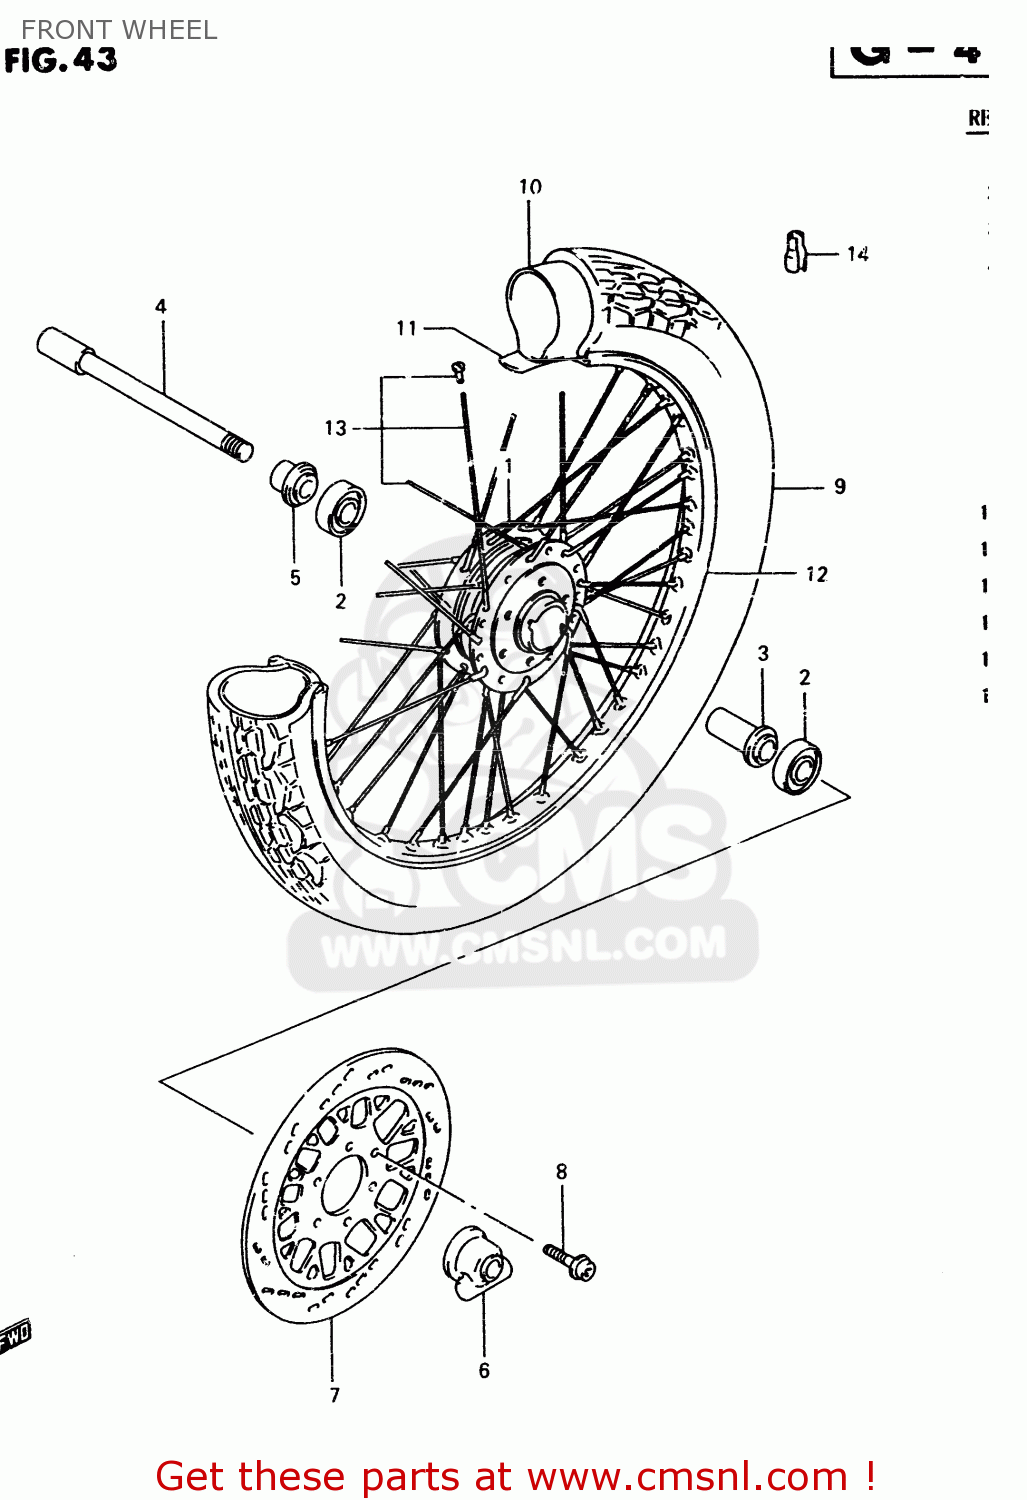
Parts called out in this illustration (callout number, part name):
1	HUB,FR WHEEL
2	BEARING
3	SPACER,FR HUB BEARING
4	AXLE,FRONT
5	SPACER,FR HUB BEARING,R
6	BOX ASSY,SPEEDOMETER GEAR
7	DISC,FR BRAKE,L
8	BOLT(8X30)
9	TIRE,FR(3.00-18 47S)
10	TUBE,INNER
11	PROTECTOR,INNER TUBE
12	RIM,FR WHEEL(1.85X18)
13	SPOKE ASSY,FR WHEEL
14	BALANCER,WHEEL (B)
